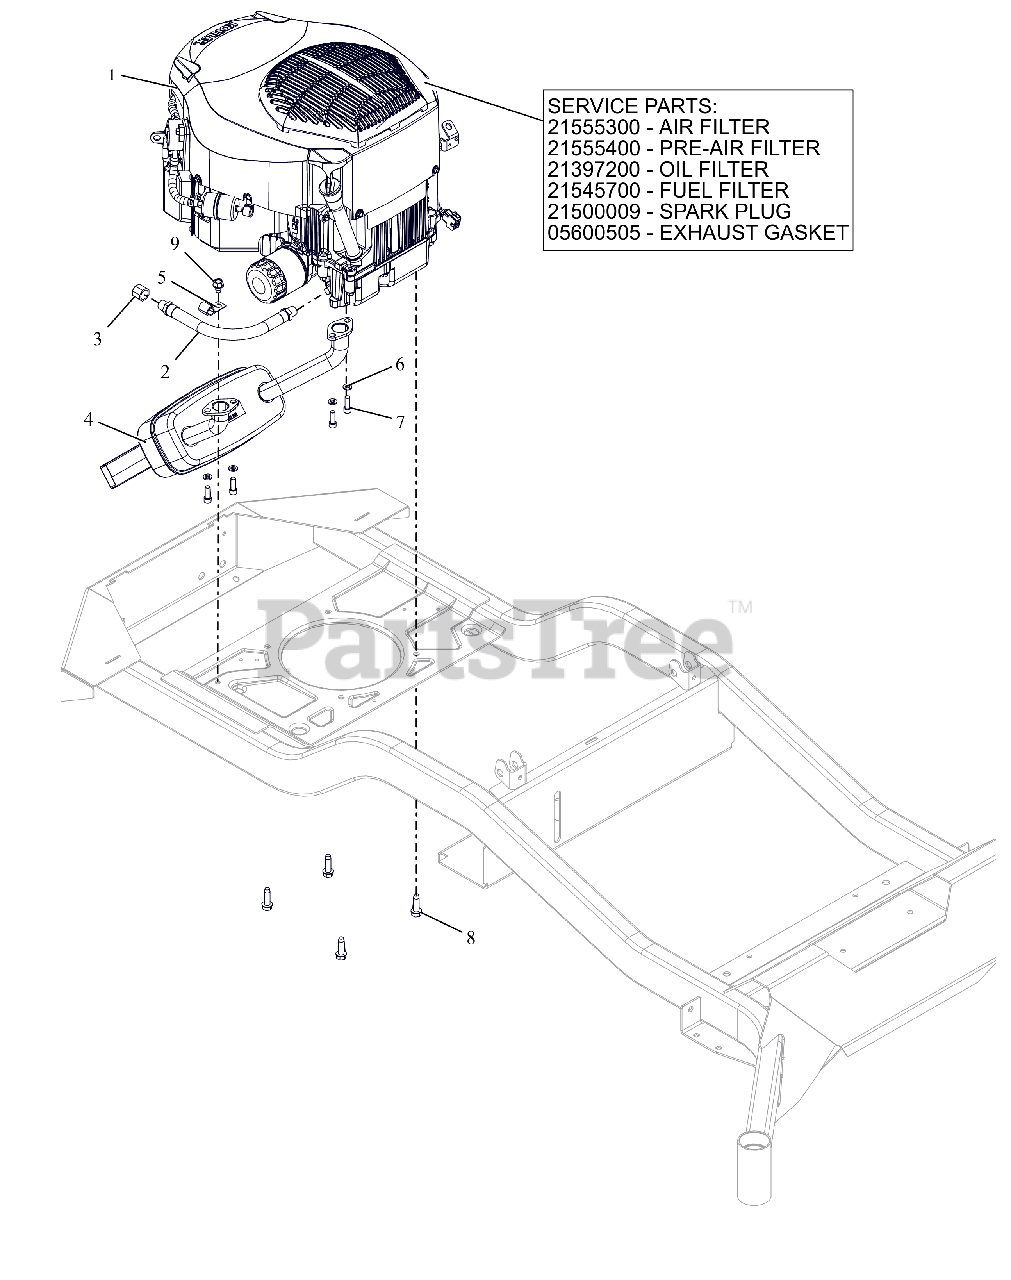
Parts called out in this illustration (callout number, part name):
1	ENGINE, KOHLER - KT740
1	AIR FILTER, KOHLER
1	PRE CLEANER, KOHLER
1	FILTER, OIL - KOH CV20
1	FILTER-FUEL KOHLER COURAGE PRO
1	PLUG, SPARK KOHLER
1	GASKET, MUFFLER COURAGE TWIN
2	HOSE,HYD .38-11-0K M6NO-M6N0
3	PIPE CAP 3/8 NPT FEMALE
4	MUFFLER, KOHLER
5	J-CLAMP
6	@WSHR-LK .31X.078 REG YWZC
7	SCR-CAP .31-18X.88 S/HD G8 ZCC
8	@SCR-TAP .38-16X1.25 HWH TR YZ
9	@SCR-TAP .38-16X.50 HWH TR YWZ
